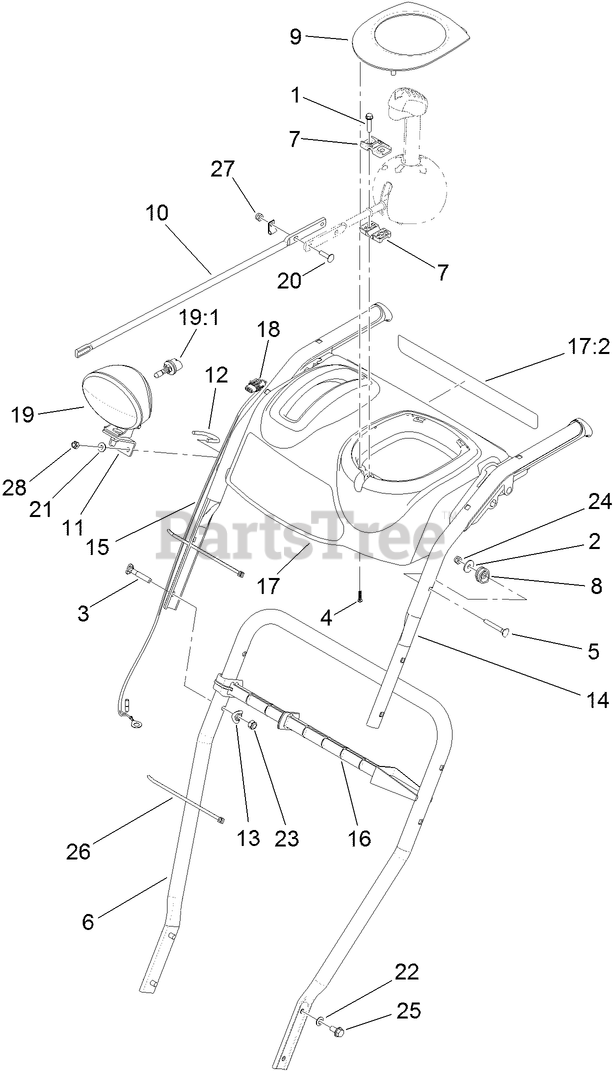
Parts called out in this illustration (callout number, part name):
1	SCREW-PLASTITE
2	WASHER-PLAIN
3	SCREW-HANDLE
4	SCREW-PPH
5	SCREW
6	HANDLE-LOWER
7	SUPPORT-ROD
8	CLAMP-CABLE
9	COVER-PANEL, CONTROL
10	ROD-CHUTE, FRONT
11	BRACKET-LIGHT
13	WASHER
15	HANDLE-UPPER, RH
16	STICK-CLEANOUT
17	PANEL-CONTROL
17:2	DECAL-WARNING
18	HARNESS-WIRE, HEADLIGHT
19	HEADLAMP ASM
19:1	LAMP-12 VOLT
20	SCREW-CARR
21	WASHER-FLAT
22	WASHER-BELLEVILLE
23	NUT-LOCK, NI
24	NUT-LOCK, NI
25	SCREW-HWHTF
26	TIE-CABLE
27	NUT-LOCK, NI
28	NUT-LOCK, NI
